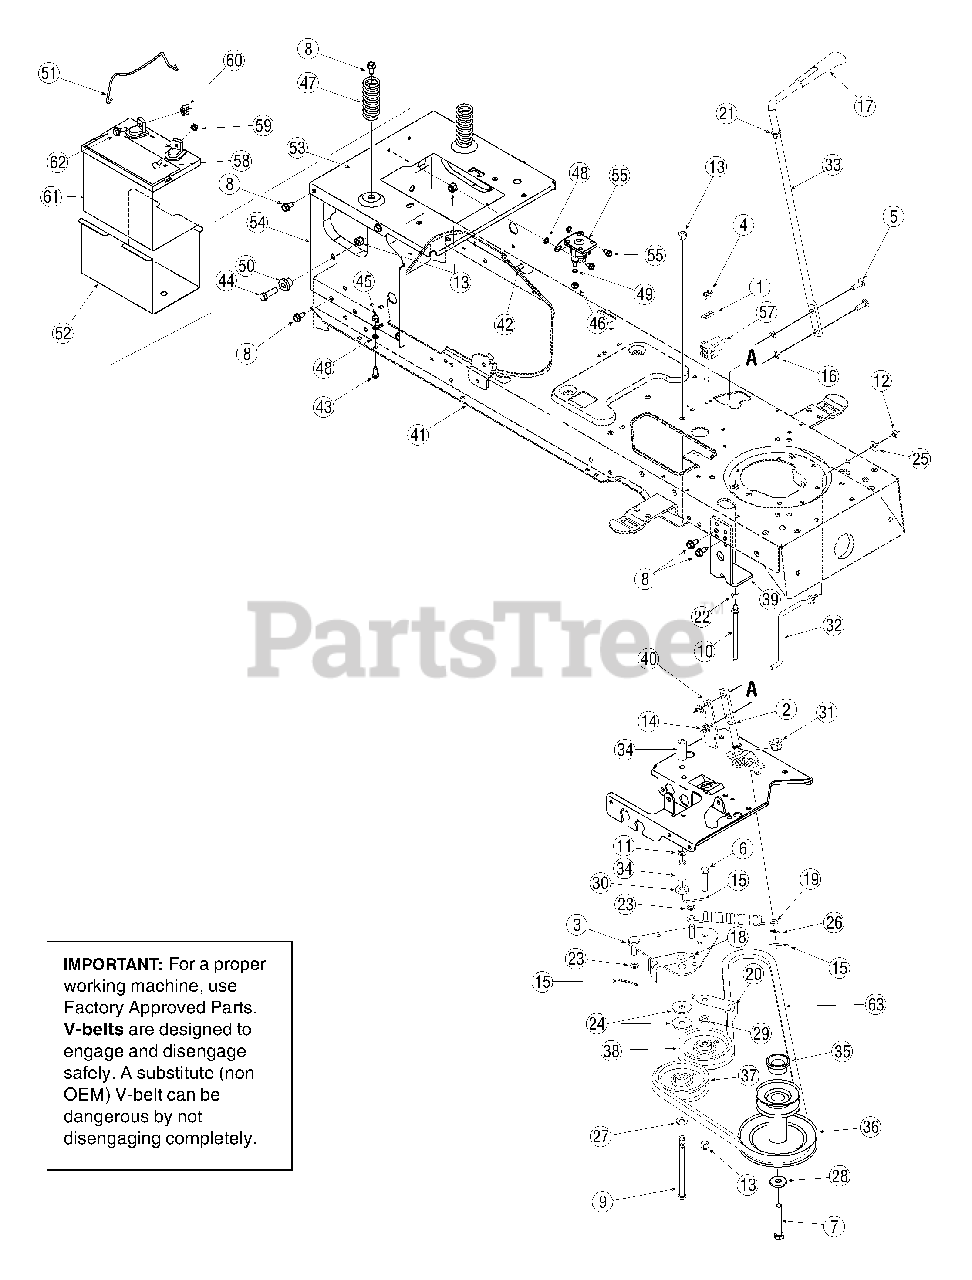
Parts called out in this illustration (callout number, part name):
1	Plate, Switch
2	Lever Assembly, Engagement
4	Screw, #10-16, 0.500
5	Screw, Carriage, 5/16-18, 1.00
6	Screw, 3/8-16, 1.75, Gr5
7	Screw, 7/16-20, 2.75, Gr5
8	Screw, 5/16-12, 0.750
9	Screw, 3/8-16, 5.50, Gr5
10	Pin, Belt Guard, 5/16 x 4.75
11	Nut, Push, 3/8
12	Nut, Flange Lock, 5/16-18, Gr F, Nylon
13	Nut, Flange Lock, 3/8-16, Gr F, Nylon
14	Nut, Flange Lock, 5/16-18, Gr5
15	Pin, Cotter, 1/8 x 1.25
16	Nut, Speed,.3125 ID
17	Knob, PTO
18	Belt Guard
19	Spring, Extension,.75 OD x 6.75
20	Belt Guard
21	Washer, Flat,.510 x.750 x.033
22	Washer, Lock, 5/16
23	Washer, Flat,.385 x.62 x.063
24	Washer, Flat,.390 x 1.500 x.134
25	Washer, Bell,.340 x.872 x.060
26	Washer, Flat,.344 x.688 x.065
27	Washer, Flat,.406 x.875 x.059
28	Washer, Flat,.450 x1.250 x.164
29	Washer, Flat,.407 x.812 x.135
30	Spacer, Shldr, 1.00 x.38 x.38
31	Bearing, Flange, Hex Split.500 ID
32	Keeper Rod, Belt
34	Spacer,.385 ID x.635 OD x 1.54
35	Spacer, 1.010 x 1.400 x.825
36	Pulley, Engine, 3.39 x 6.12 Diameter
37	Pulley, Idler, V-type 5/8 x 4.0 Diameter
38	Pulley, Idler, 3.50 Diameter
43	Screw, 1/4-20, 0.750
44	Screw, 3/8-16, 1.25, Gr5
45	Nut, Flange Lock, 1/4-20, Gr F, Nylon
46	Nut, Hex, 1/4-20, Gr5
47	Spring, Compression, 1.28 OD x 3.125
48	Washer, Lock, 1/4, External
49	Washer, Lock, 1/4
50	Spacer, Shoulder,.38 x 1.0 x.70
51	Hold Rod, Battery
55	Screw, 1/4-20, 0.50
56	Solenoid, 12V, 100 Amp
57	Switch, Interlock
58	Screw, Carriage, 1/4-20,.75, Gr5
59	Nut, Sems, 1/4-20
60	Nut, Wing, 1/4-20
61	Battery, 235 CCA
62	Screw, Shoulder,.250 x.150, 1/4-20
63	V-Belt, PTO
